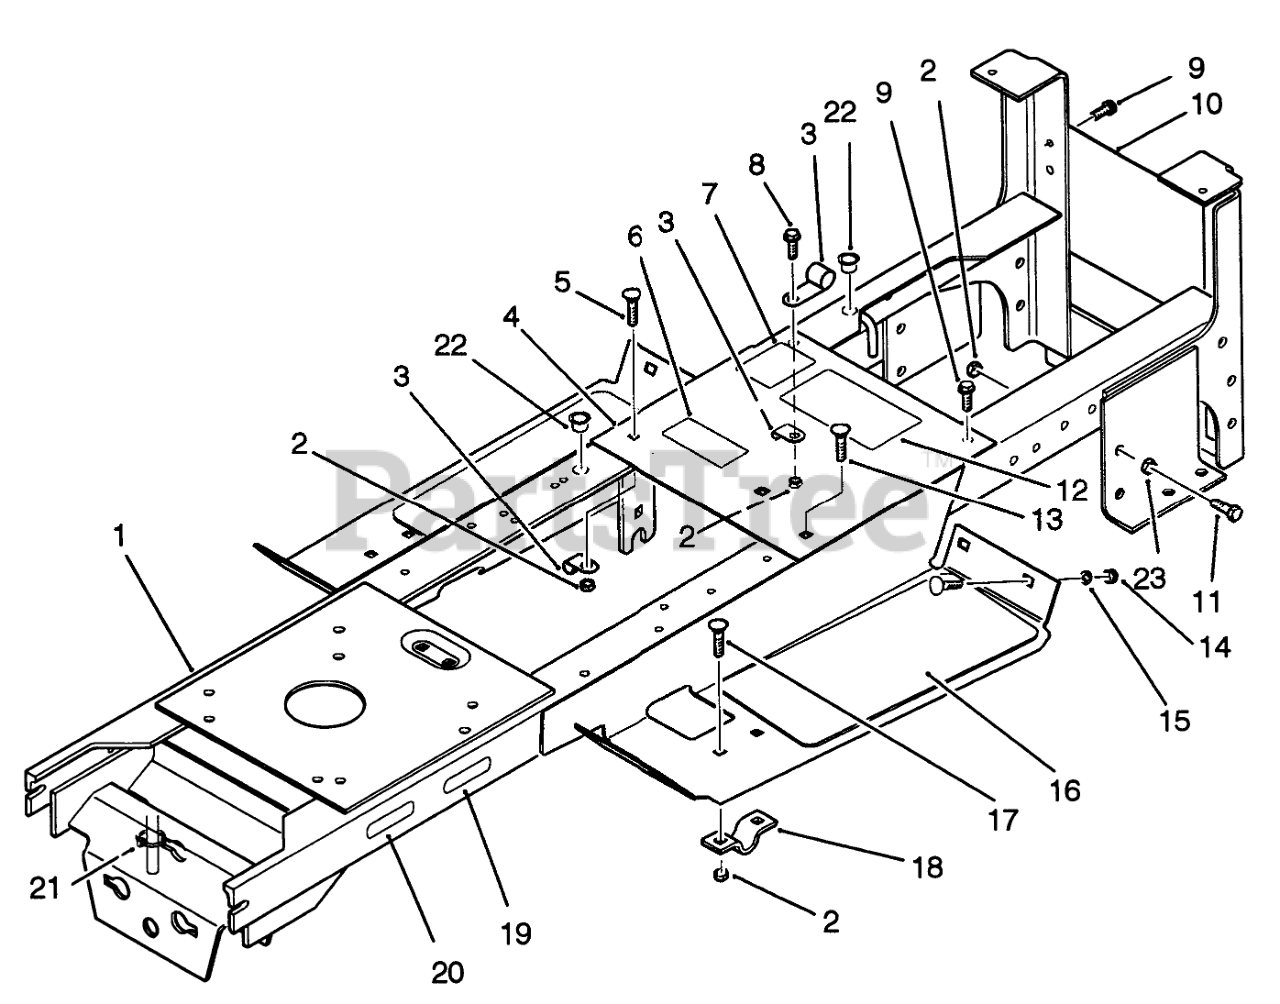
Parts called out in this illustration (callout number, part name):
1	WEDMT-FRAME R
2	NUT-LOCK, NI
3	THROTTLE CONTROL CLP
4	Panel
5	Bolt-Carriage
6	DECAL-DANGER
7	DECAL-PARKING BRAKE
8	Bolt
9	SCREW
10	PANEL-REAR R
11	SCREW-HH
12	DECAL-DANGER
13	Bolt-Carriage
14	NUT-HEX
15	WASHER - FLAT YZ
16	PAD FOOTREST
17	Bolt-Carriage
18	CLAMP
19	Decal-Attac-O-Matic
20	DECAL-INSTALL BELT
21	PLASTIC TIE
22	BUSHING
23	NUT-JAM
